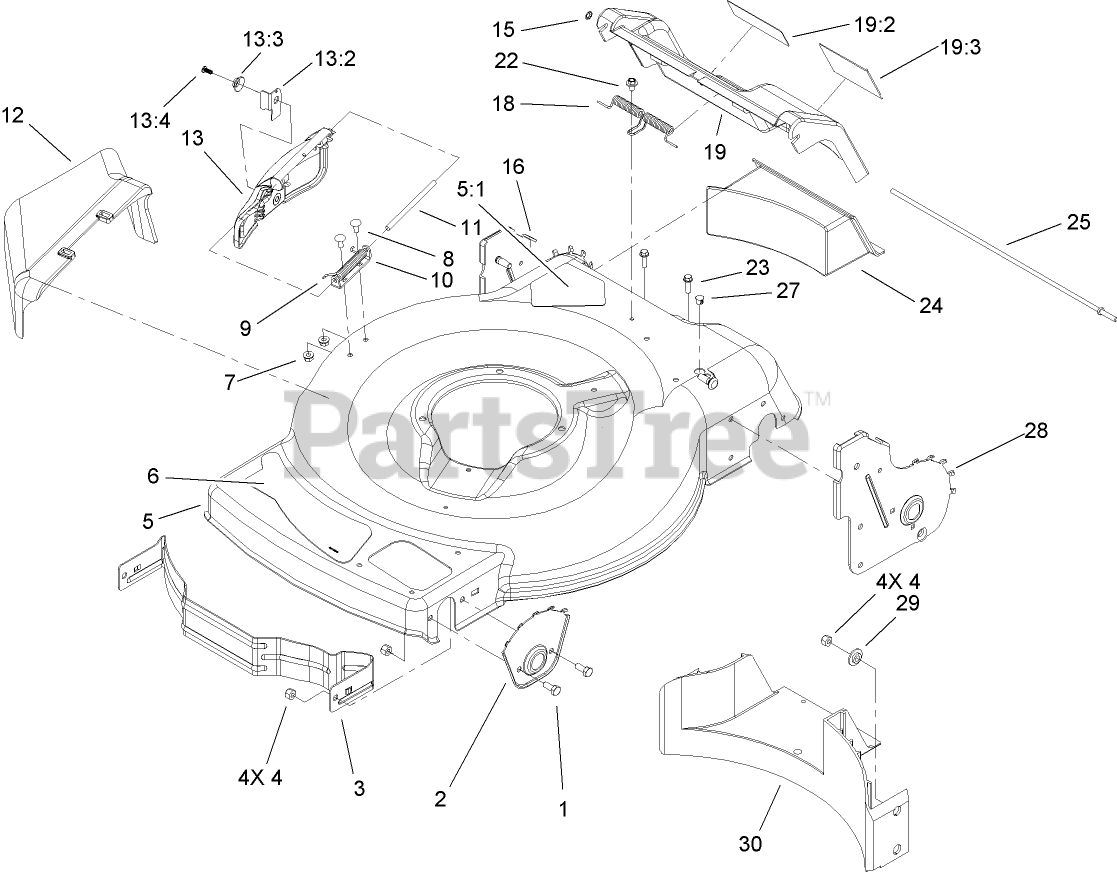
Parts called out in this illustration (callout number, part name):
1	SCREW-HH
3	BAFFLE-FRONT
4	NUT-LOCK, NI
5:1	DECAL-DANGER
6	DECAL-DECK
7	NUT-HHF
8	SCREW-CARR
9	SPRING-TORSION
12	CHUTE-DISCHARGE, SIDE
13	DISCHARGE DOOR ASM
13:2	LATCH-DOOR
13:3	CAP-DOOR
13:4	SCREW-PLASTITE
15	NUT-PUSH
18	SPRING-DOOR, REAR
19	REAR DOOR ASM
19:2	DECAL-WARNING
19:3	DECAL-WARNING
22	SCREW AND WASHER ASM
23	SCREW-HWH
24	PLUG-DISCHARGE, REAR
25	ROD-PIVOT, REAR DOOR
27	PLUG-DOME
29	WASHER-STEPPED
30	BAFFLE-REAR
